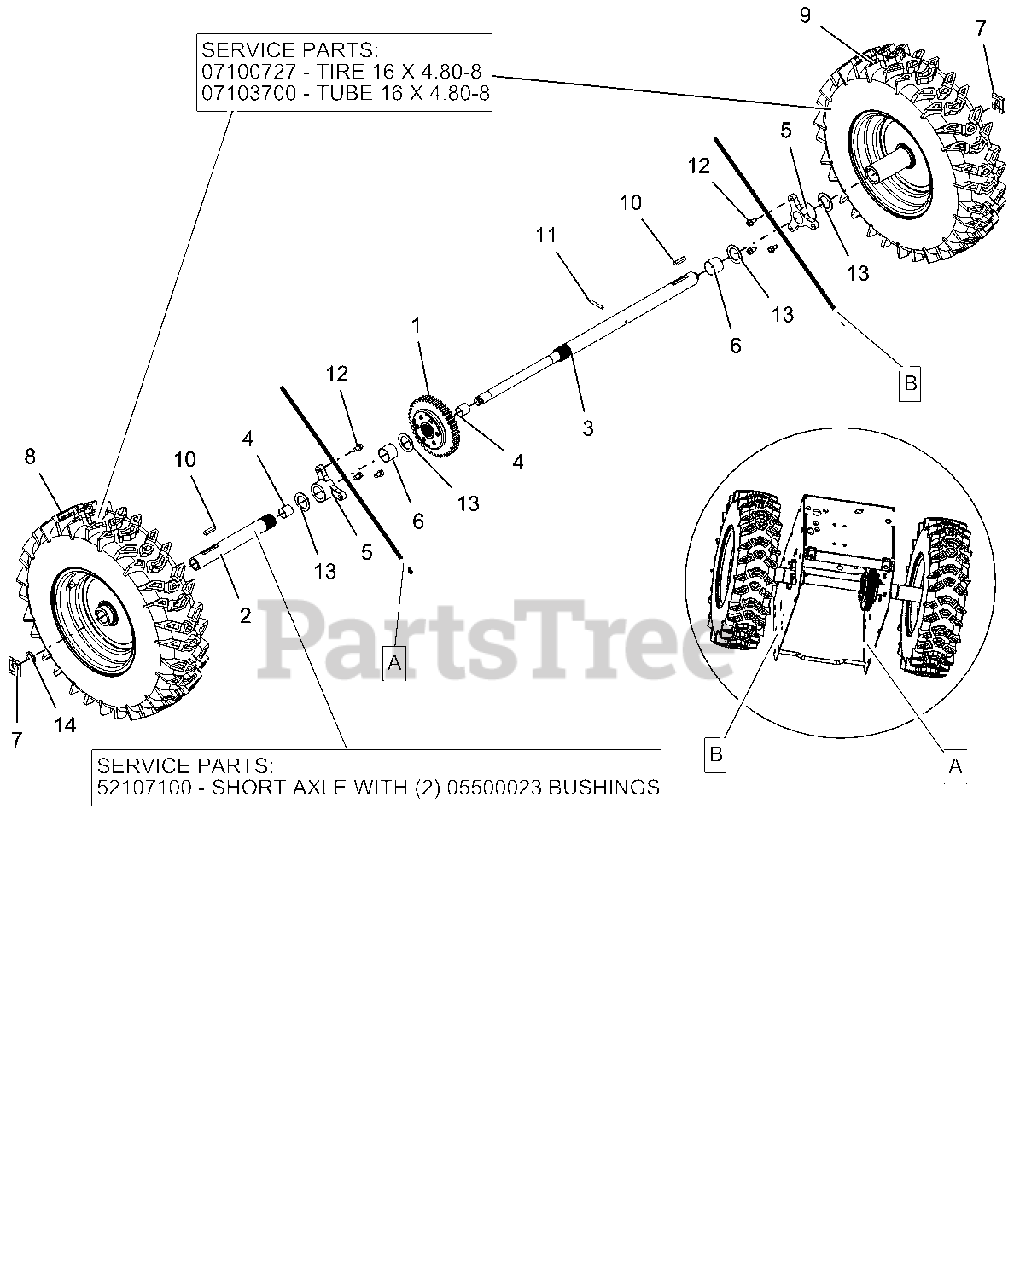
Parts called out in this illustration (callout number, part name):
1	DIFFERENTIAL, AUTOMATIC
2	BSHG-SLV .706X.764X.75 BRZ
2	AXLE, SHORT - DIFFERENTIAL
2	KIT, SHORT AXLE W/BUSHINGS
3	AXLE, LONG - DIFFERENTIAL
4	BSHG-SLV .706X.764X.75 BRZ
5	BUSHING, AXLE
6	BSHG-SLV, 1.012X1.125X.875
7	CLIP, SNAP .625 DIA
8	TIRE, 4.80-8 K478
8	TUBE
8	TIRE/WHEEL,RH 16X4.8-8 DIFF T2
9	TIRE, 4.80-8 K478
9	TUBE
9	TIRE/WHEEL,LH 16X4.8-8 DIFF T2
10	KEY-RECT .25X.188X1.00
11	PIN-ROLL .188X1.25
12	SCR-TAP .25-20X.50 HWH TR YWZ
13	WSHR-FL-STL 1.010X1.505X.062YZ
14	RG-RTNG-EXT .625X.042
